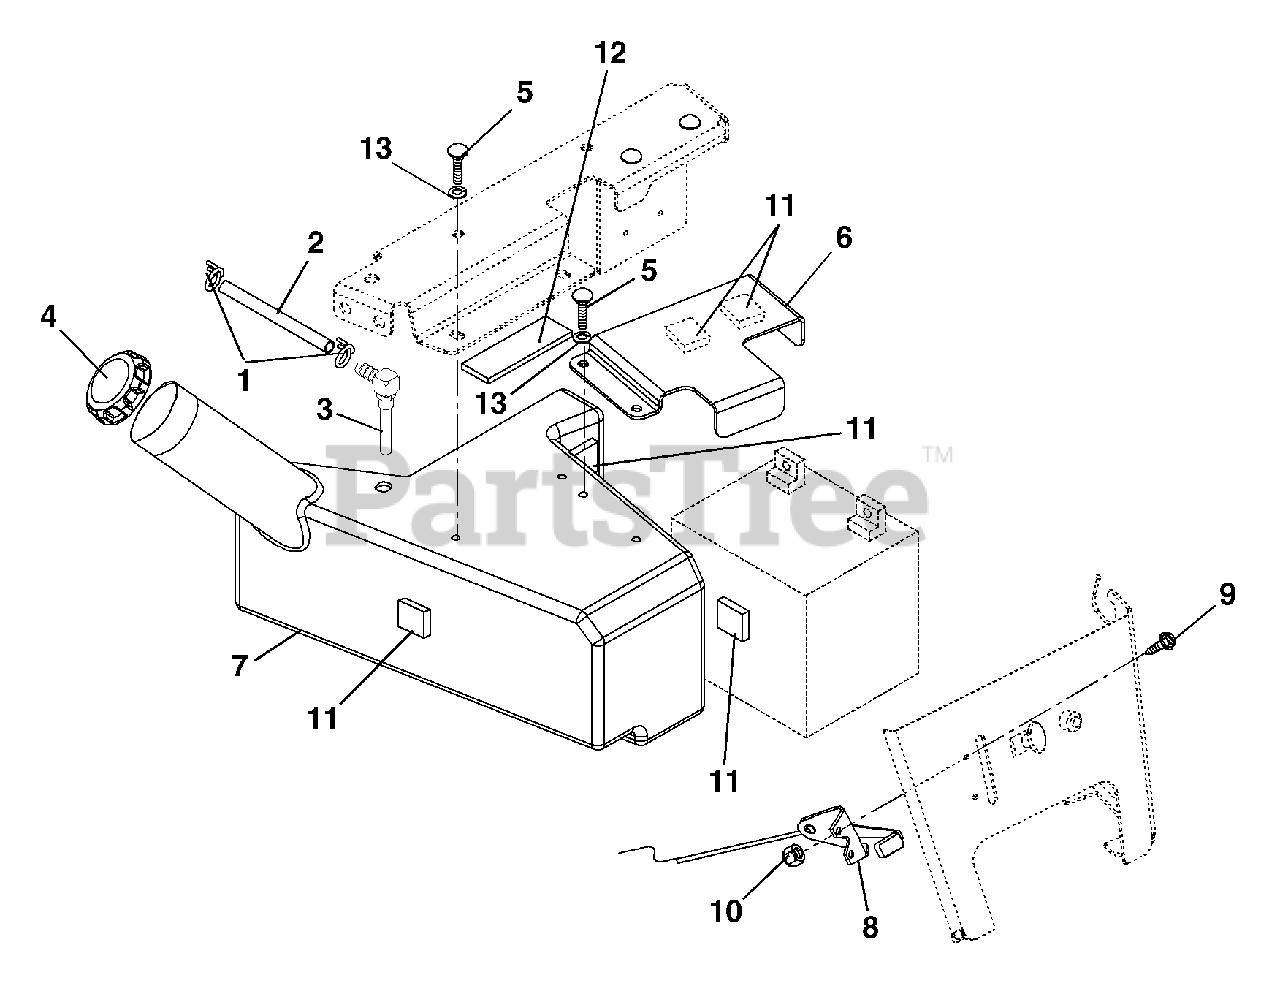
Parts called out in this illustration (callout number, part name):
1	CLAMP-HOSE WIRE .490/.510X.116
2	GAS LINE-BULK 1/4" I.D.
3	TANK FITTING
4	FUEL CAP
5	BLT-SERHFWH .25-20X.75 YWZC
6	BRACKET-BATTERY
7	TANK-FUEL
8	THROTTLE CABLE
9	@SCR-MCH 10-24X.50 HWH YWZC
10	@NUT-LK-NYL 10-24 W/INSRT YWZC
11	PAD, FOAM
12	VHB TAPE 4941F
13	@WSHR-LK .31X.078 REG YWZC
